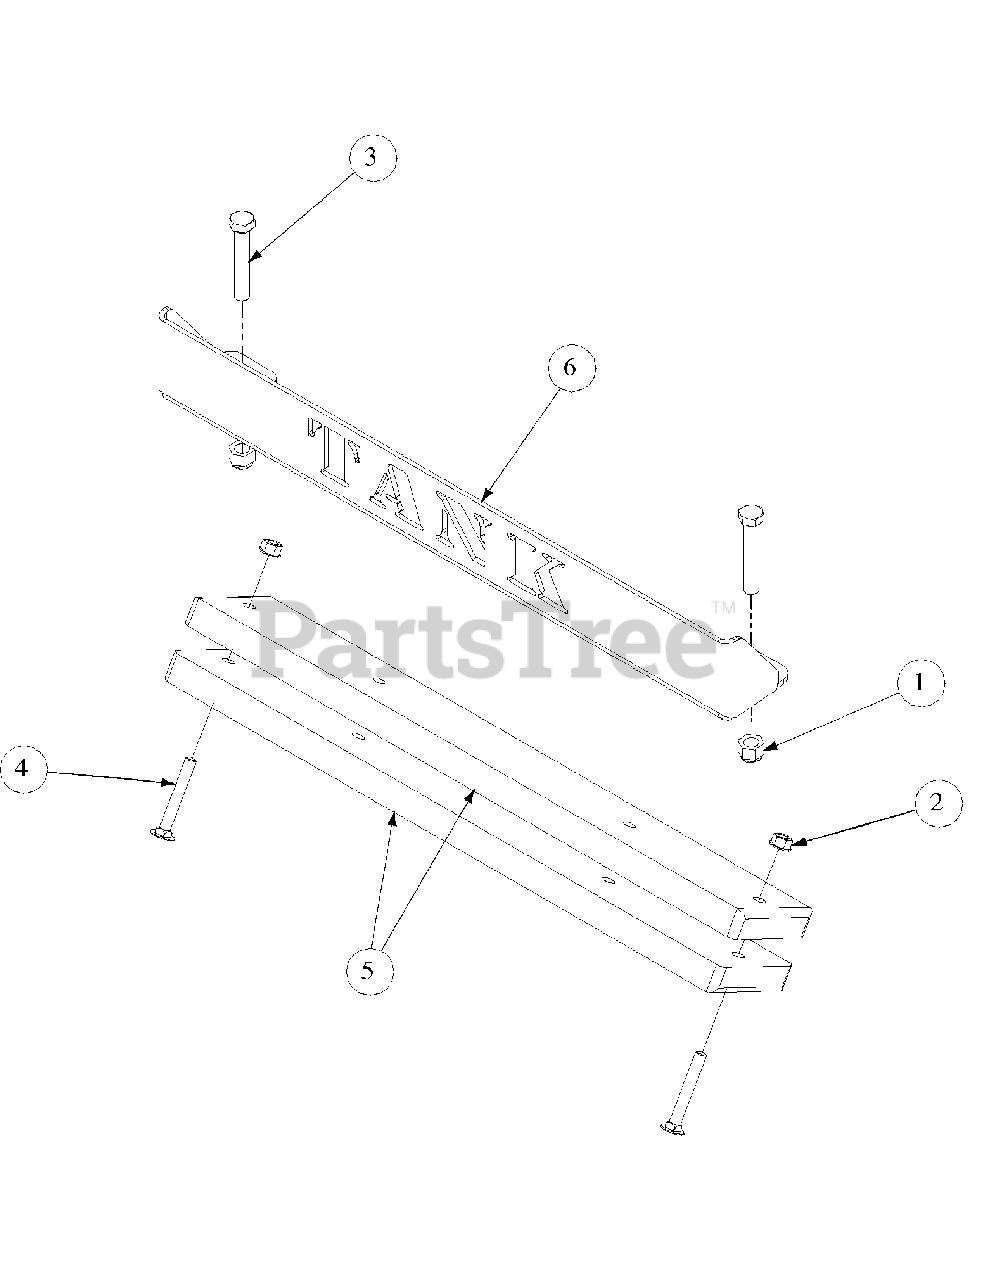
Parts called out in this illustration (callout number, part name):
1	Hex Nut, 1/2-13, Insert Lock
2	Nut, Hex 3/8-16 Flange Lock
3	HHCS, 1/2-13, 3.00
4	Carriage Bolt, 3/8-16 x 2.75
5	Bar, Weight
6	Rear Bumper Plate
